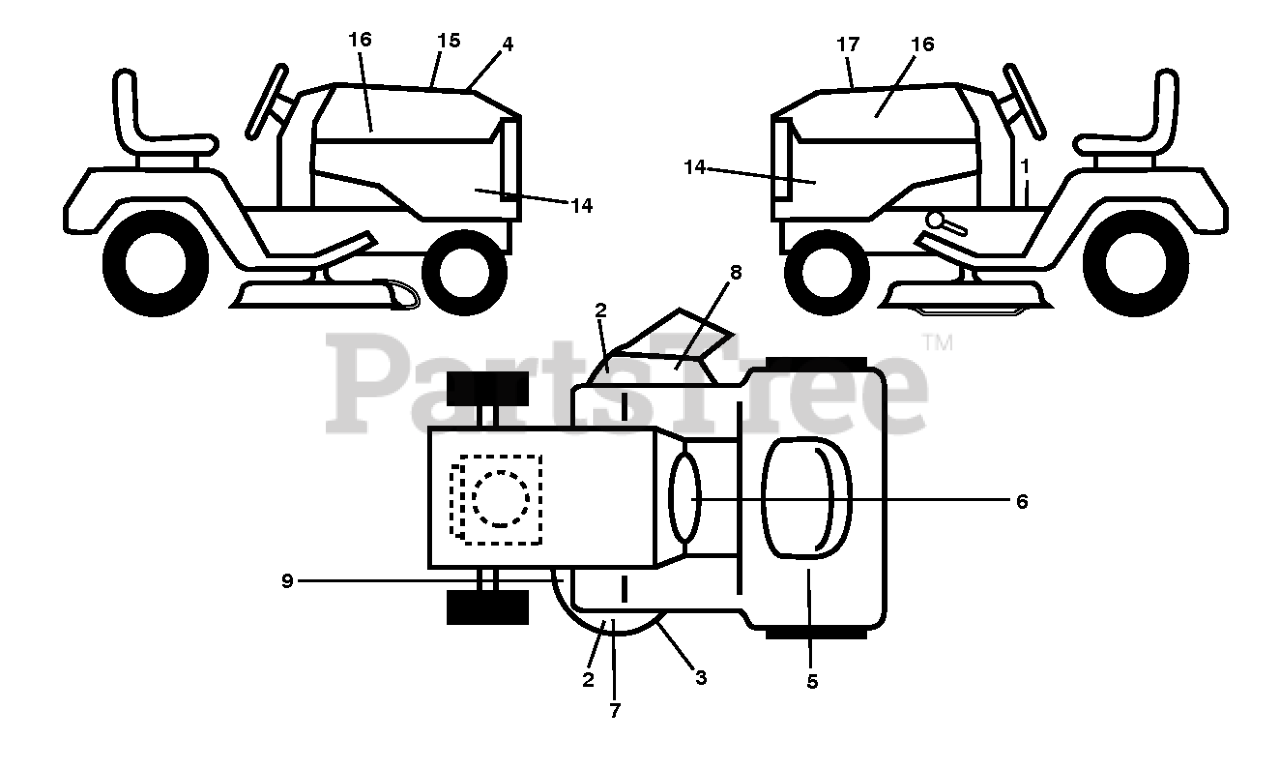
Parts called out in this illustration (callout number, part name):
1	DECAL.FENDER.WARNING.ENGLISH
2	DECAL.DECK.CLEARCUT.NOSTEP
3	DECAL.MOWER.SCH.48/54.PREM
4	DECAL.WARNING.CUST.RESP.E85.
5	DECAL.RESERVEFUELSELCTR.ENG
6	DECALS.WARN.CA.SPKARREST/PROP
7	DECAL DECK DECAL DECAL.48DECK.
8	DECAL.TRACT/ZTR.DECKWARN.HUSQ
9	DECAL DECK DECAL DECAL.DECK.WA
14	DECAL TRACTOR SIDE PANEL DECAL
15	DECAL.WARNING.CUST.RESP.E85.
16	DECAL.BADGE.170MM.TEXTLOGO.
17	DECAL.RPL.KW.FR.TGB.48F.K66AL
